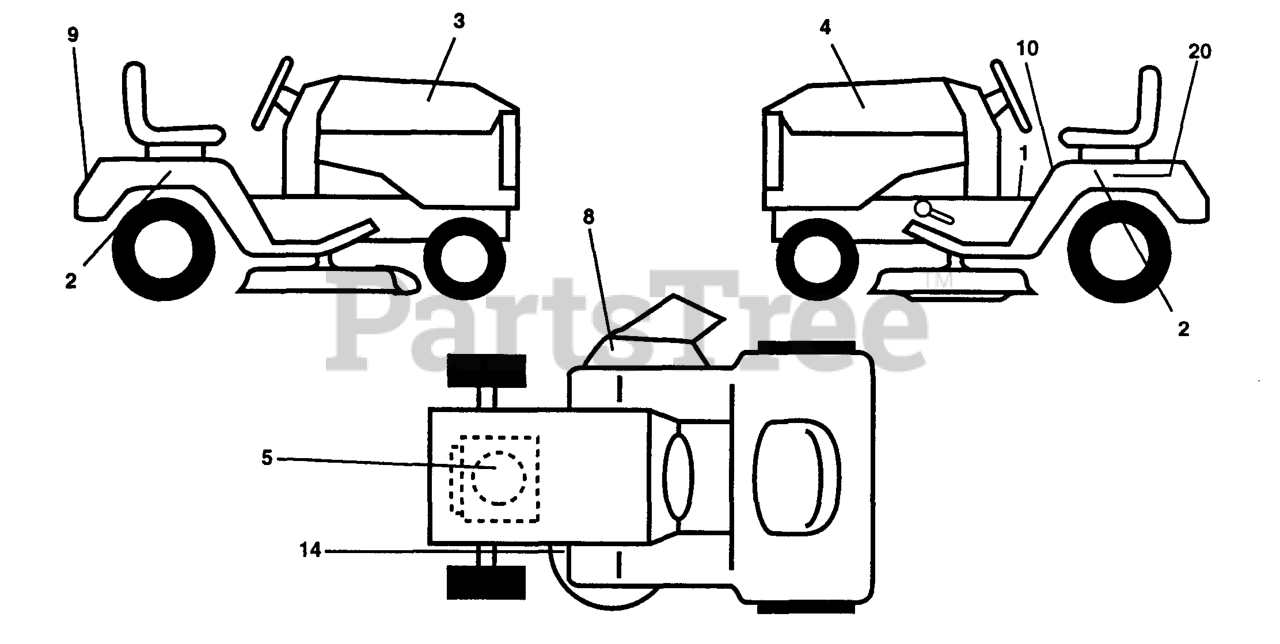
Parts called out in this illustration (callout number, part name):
3	DECAL HOOD RH
4	DECAL HOOD LH
5	DECAL HP ENGINE
8	DECAL WARNING (ENGLISH/FRENCH)
9	DECAL FENDER HUSQ
10	DECAL FENDER DANGER
14	DECAL V BELT SCHEMATIC
20	DECAL BTRY SYMBOLS
